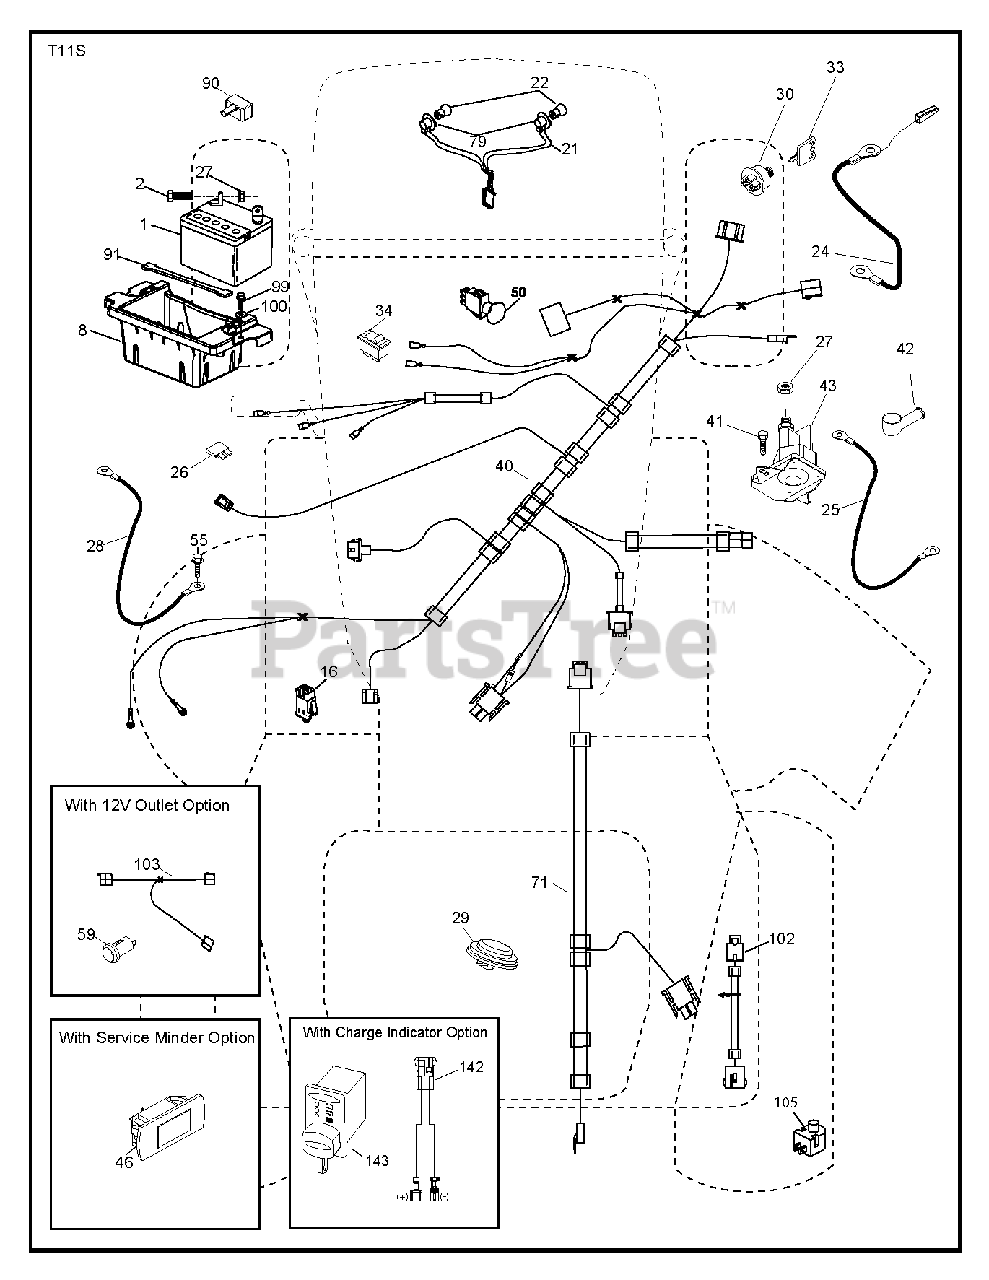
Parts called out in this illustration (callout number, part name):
1	Battery, Dry 30 Amp
2	BOLT.HEX.1/4.X.3/4.DICHROMATE
8	BOX.BATTERY.MOUNT.FRONT.LT
16	SWITCH INTERLOOK PUSH-IN
21	HARNESS.LIGHT W/4152J BULBS
24	CABLE.BATT.POS.WIRE.TG.DA SOL
25	CABLE.STARTER.6G.BL/RED.17.5
26	FUSE 20AMP
27	NUT
28	CABLE GROUND 6 GA 21" 90T BLK
29	SWITCH.SEAT.DELTA.OPC.
30	SWITCH.IGN.DELTA.W.LGH.ROS
33	KEY.CHAIN.BLISTER.PACK.GEN.INT
40	HARNESS-CHASSIS SUB
41	SCREW
42	TERMINAL COVER
43	SOLENOID.W/BRASS.PLUNGER
46	RP GUAGE.SRVCMNDR.HRMTR.
50	RB PTO.SWITCH.8 TERMINAL.BLACK
55	SCREW 5/16"
71	HARNESS.IGN.DASH.HUQ/P
79	BULB HOLDER ASM.
90	COVER.TERMINAL.BATTERY
91	STRAP.BATTERY.MOUNT.FRONT(2 2)
99	SCREW HEXWSHR 1/4-20X3/4
102	REVERSE SWITCH
105	HARNESS PIGTAIL PCH TEX ROS
